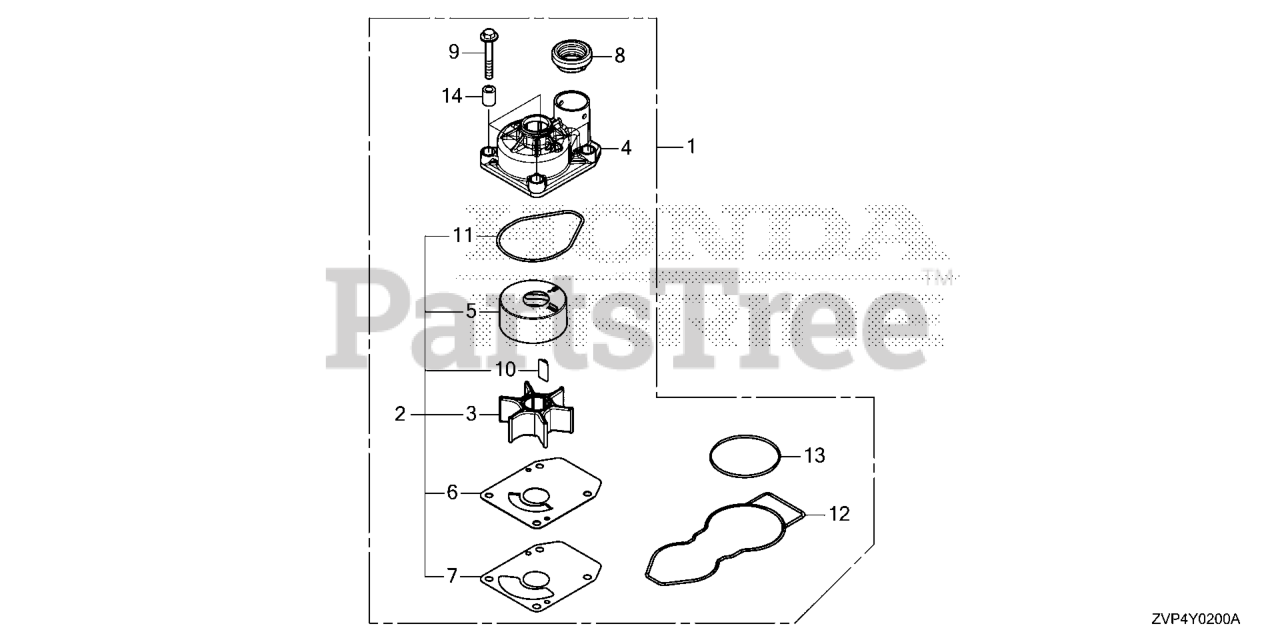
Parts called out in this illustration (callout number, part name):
1	PUMP KIT A, IMPELLER
2	PUMP KIT B, IMPELLER
2	PUMP KIT, IMPELLER (B)
3	IMPELLER, PUMP
4	HSG, IMPELLER
5	LINER, WATER PUMP
6	COVER, IMPELLER
7	GASKET B, IMPELLER
8	RING
9	BOLT-WASHER (8X60)
10	KEY, WOODRUFF
11	O-RING, WATER PUMP
12	O-RING, HSG PUMP
13	O-RING (79.4X2.4)
14	COLLAR, DISTANCE
